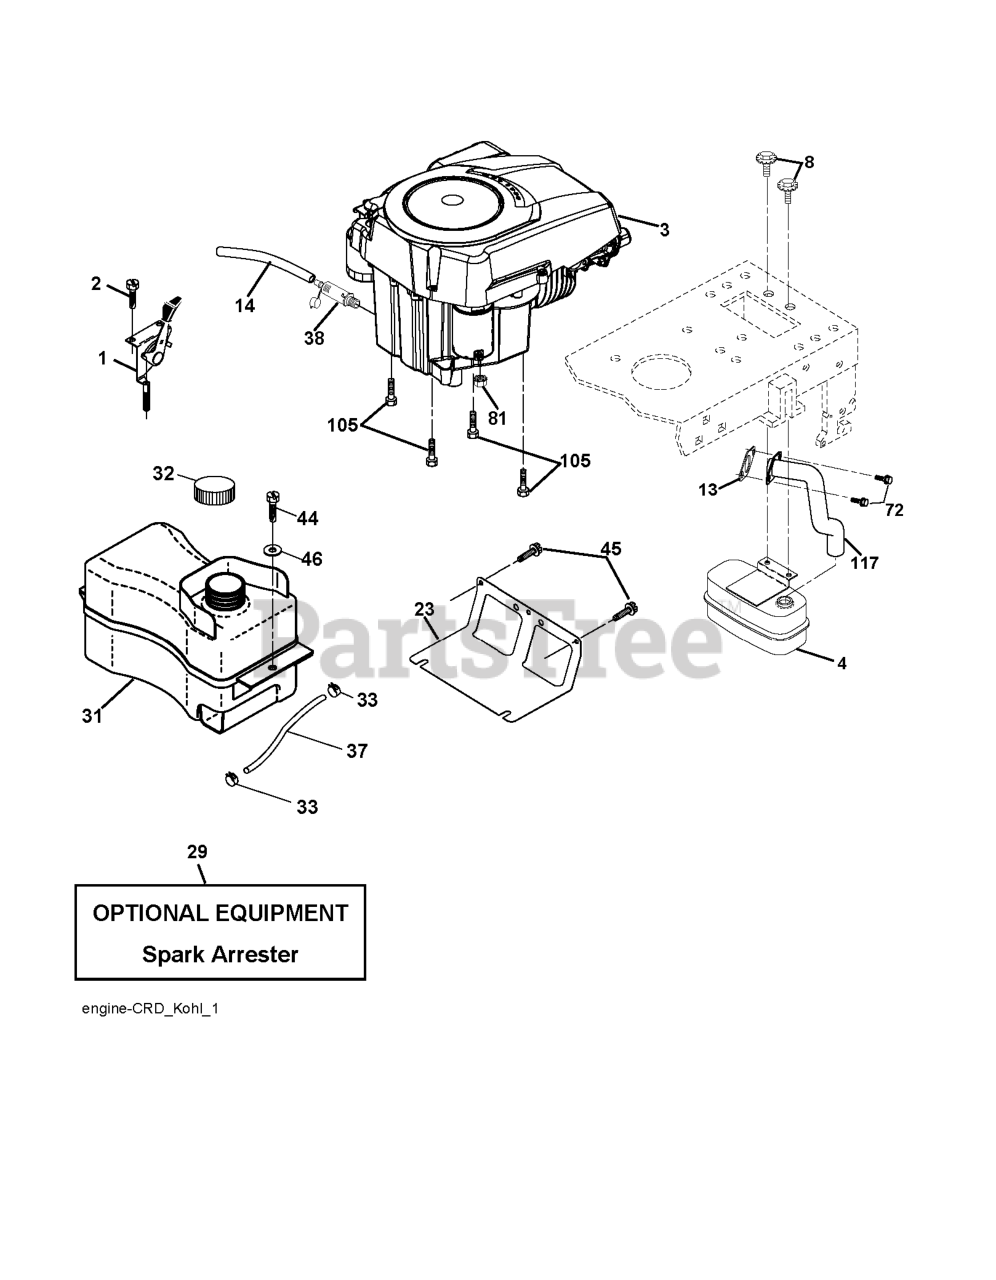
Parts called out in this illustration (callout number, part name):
1	CONTROL.TH/CK.C.
2	SCREW.#10 X 0.750.BOS THREAD
4	MUFFLER.SINGLE.CYL.KOHL/B&S
8	BOLT.5/16-18UNCX3/4 W/SEMS.BLK
13	GASKET.EXHAUST.KOHLER
14	TUBE, DRAIN OIL ASM.
23	SHIELD.BROWNING.DBR.GUARD
29	KIT.SPARK ARRESTOR 794945 B&S
31	RP TANK FUEL FRT 1.5 GAL
32	FUEL CAP
33	HOSE CLAMP
37	LINE.FUEL.20
38	PLUG DRAIN OIL EASY
44	SCREW HEXWSHR 1/4-20X3/4
45	SCREW, 3/8-16X3/4
72	SCREW.SOCKET HD.5/16-1
81	NUT
105	SCREW 3/8-16X1
117	RP.TUBE.EXHAUST.KOHL.COURAGE
